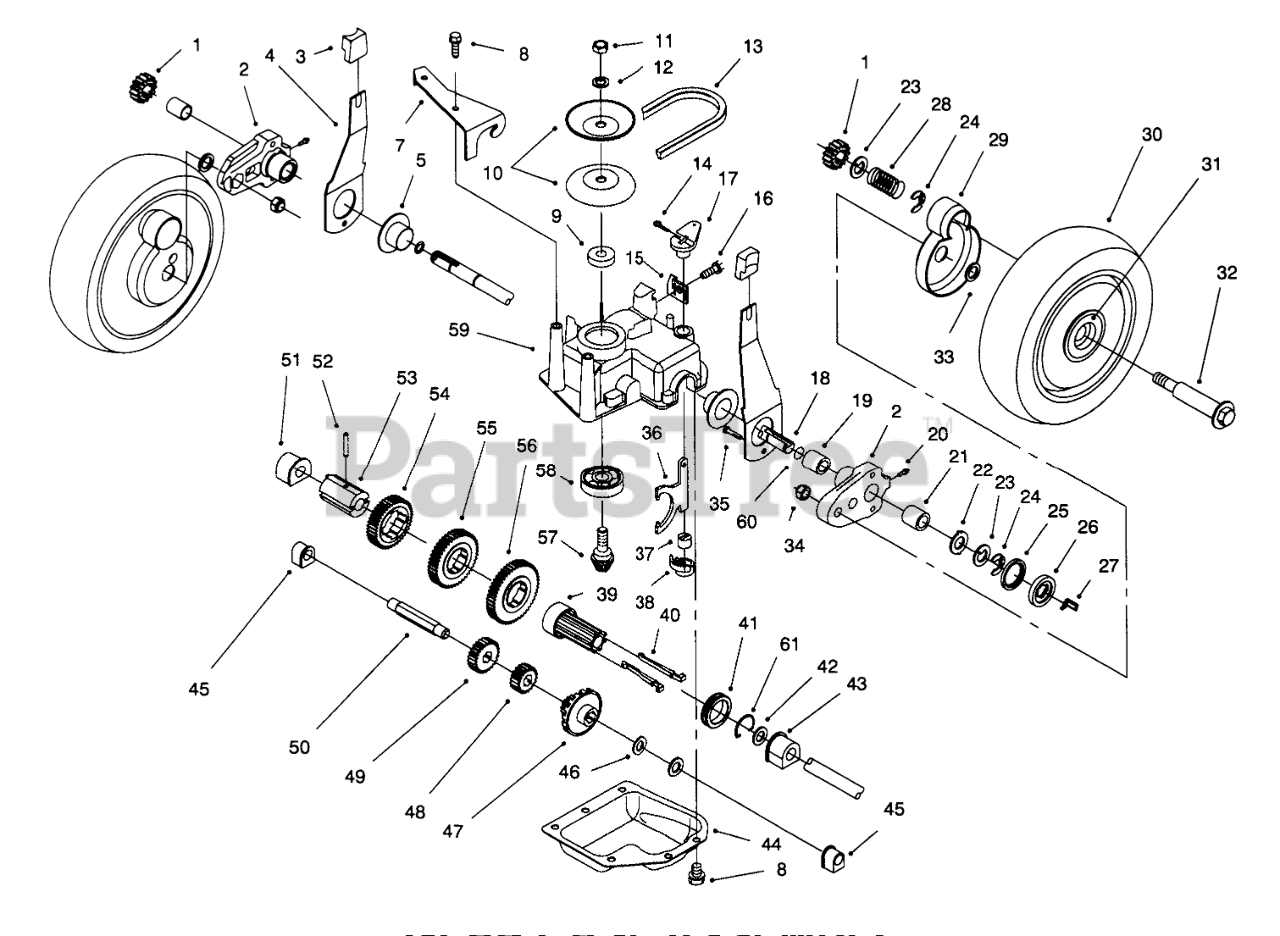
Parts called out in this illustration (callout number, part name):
1	GEAR-PINION
2	Pivot Arm Assembly(Incl.Ref # 19, 20, & 21)
3	KNOB-ARM
4	SPRING ARM ASM SP
5	CAP-END
7	Bracket-Guide
8	SCREW-HWHTF
9	SPACER
10	Pulley Half
11	NUT-HEX
12	WASHER-FLAT
13	V-BELT E
14	PIN-COTTER
15	CLAMP-CABLE
16	SCREW-HWHTF
17	LEVER-SHIFT
18	SHAFT-OUTPUT
19	BUSHING
20	FITTING-GREASE
21	BEARING-ROLLER
22	WASHER-ARM, PIVOT
23	WASHER-THRUST, KEYED
24	RING-CLIP, LOCKING
25	RING-FRICTION
26	WASHER-CLUTCH
27	KEY-ROCKING, LH
28	SPRING-COMPRESSION
29	COVER-WHEEL
30	Wheel-Tire & Gear Ass-y(Incl. Ref. # 31)
31	BUSHING
32	BOLT-WHEEL
33	SPACER-COVER, WHEEL
34	NUT-LOCK
35	SCREW-HWH
36	YOKE-SHIFT
37	BUSHING-YOKE
38	RETAINER-FORK, SHIFT
39	SLEEVE-KEY, SHIFT
40	KEY-SHIFT
41	COLLAR-SHIFT
42	WASHER-PLAIN
43	BUSHING-OUTPUT
44	Cover-Gearcase
45	BUSHING
46	WASHER-THRUST
47	Gear-Bevel
48	PINION-20T
49	PINION-25T
50	SHAFT-INTERMEDIATE
51	BUSHING
52	PIN-SPRING
53	SLEEVE-GEAR
54	GEAR-39T
55	GEAR-44T
56	GEAR-49T
57	Gear-Pinion
58	BEARING-BALL
59	CASE-GEAR, UPPER
60	O-RING
61	CLIP-SPRING
